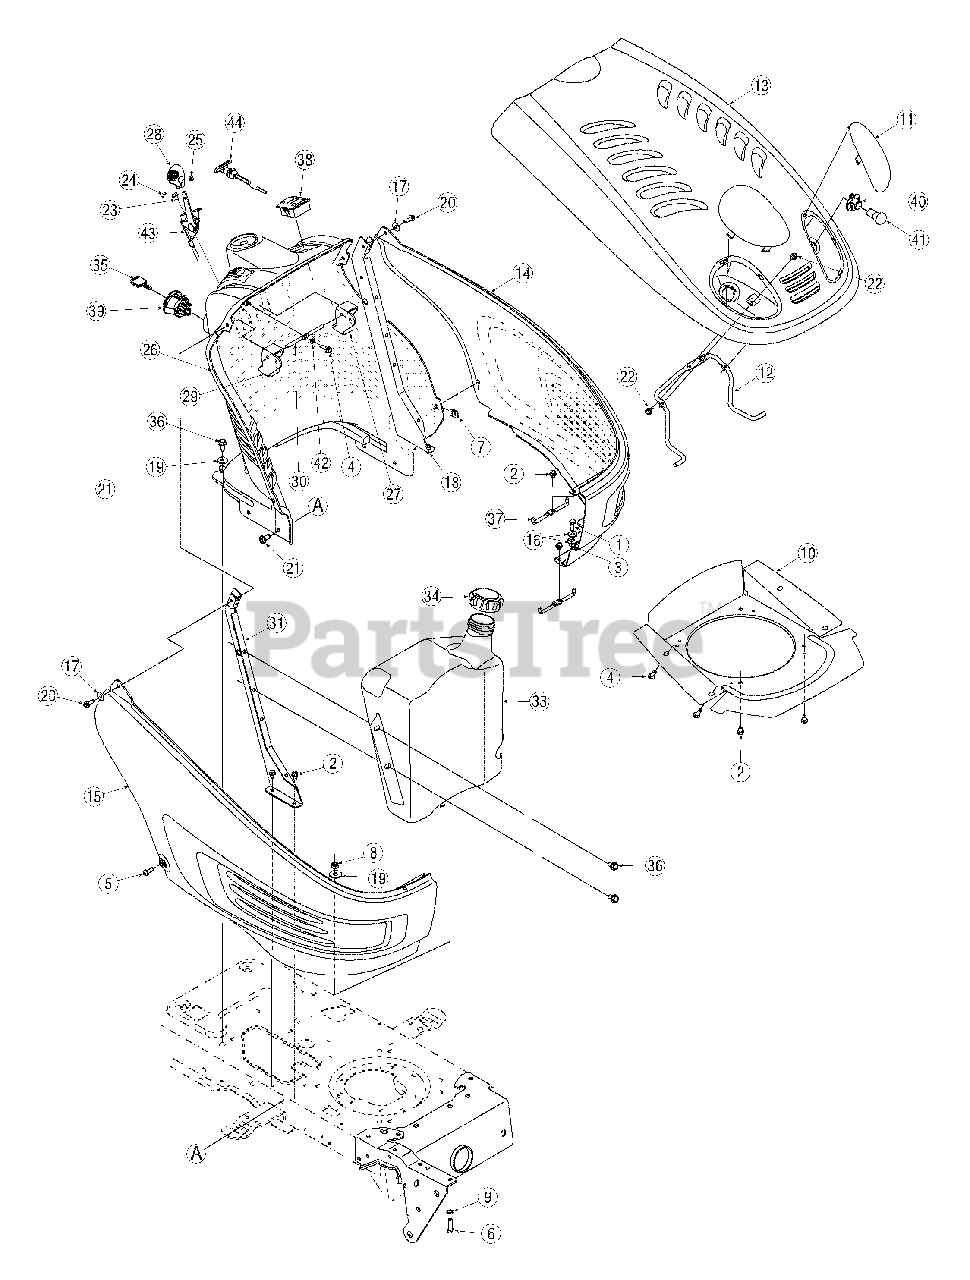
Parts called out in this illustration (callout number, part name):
1	Hex Cap Screw, 1/4-20 x.75
2	Self-tapping Screw, 1/4-20 x.5
3	Flange Lock Nut, 1/4-20
4	Self-tapping Screw, 1/4-15 x.75
5	Pan Phillips Screw, 1/4-20 x.75
6	Hex Cap Screw, 5/16-18 x 1.0
7	U-type Speed Nut, 1/4-20
8	Flange Lock Nut, 5/16-18
9	Speed Nut
11	RH Headlight Lens
12	Hood Support Rod
13	Hood
14	LH Side Panel
15	RH Side Panel
16	Flat Washer,.28 x.74 x.063
17	Flat Washer,.283 x.75 x.030
19	Flat Washer,.349 x 1.0 x.063
20	Self-tapping Screw, 1/4-20 x.75
21	Self-tapping Screw, 5/16-18 x.75
22	Self-tapping Screw, 1/4-20 x.625
23	Self-tapping Screw, 1/4-14 x.625
24	Screw, #8-32 x.375
25	Hex Nut, 8-32
26	Dash Panel
27	Parking Brake Lever
28	Throttle Control Knob
29	Cruise Control Lever
30	Brake/Cruise Pivot Rod
33	Fuel Tank, 3-gallon
34	Fuel Cap
35	Ignition Key w/ plastic cover
36	Self-tapping Screw, 5/16-18 x.75
37	Side Panel Support
38	Systems Indicator Monitor, Ammeter
39	Ignition Switch
40	Lamp Socket
41	Lamp, 12V
42	Flat Washer,.281 x.50 x.063
43	Throttle Control/Cable
44	Choke Knob/Cable
